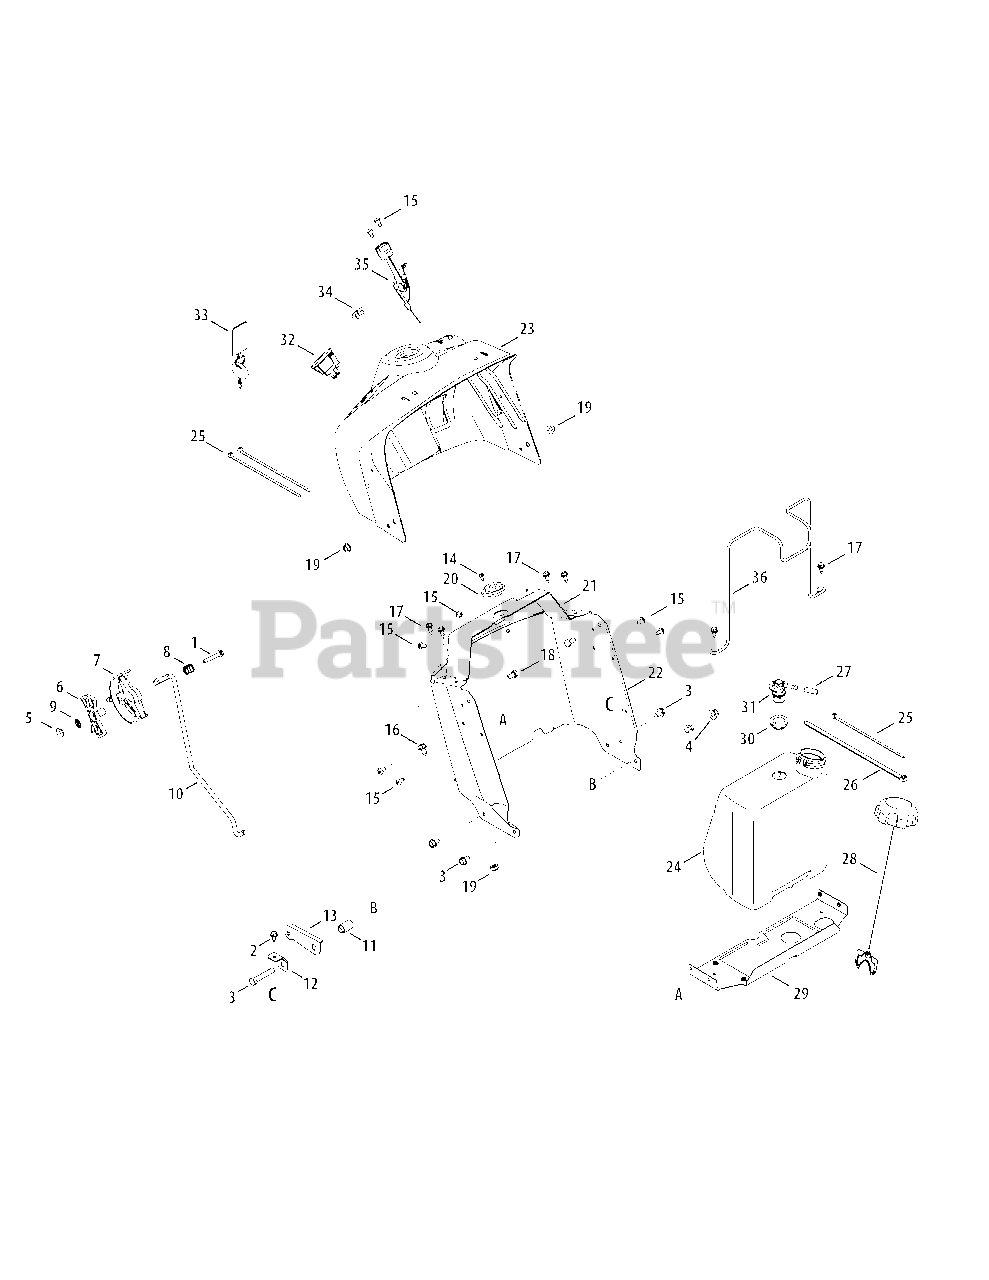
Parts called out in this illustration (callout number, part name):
1	Hex Head Screw, 1/4-20 x 1.50
2	Self-Tap Screw, 1/4-20 x .625
3	Hex Head Screw, 3/8-16 x 2.00
4	Flange Lock Nut, 3/8-16
5	Top Lock Weld Nut, 1/4-20
6	Index Control
7	Shift Lever
8	Compression Spring, .685 x .63
9	Internal Lock Washer, 1/4
10	Speed Control Rod
11	Flange Spacer, .390 x .671 x 1.095
12	Speed Latch Tab
13	Speed Latch
14	Screw, #10
15	Self-Tap Screw, 1/4-20
16	Self-Tap Screw, 5/16-18
17	Hex Washer Screw, 1/4-20 x .625
18	Hex Head Screw, 5/16-18
19	Flange Lock Nut, 5/16-18
20	Steering Column Bearing
21	Steering Support Bracket
22	Lower Dash
23	Upper Dash Panel
24	Fuel Tank
25	Cable Tie, 3/16 x 7.4"
26	Cable Tie, 36" Lg.
27	Vent Hose
28	Fuel Cap
29	Gas Tank Support Bracket
30	Rubber Grommet
31	Fuel Rollover Valve
32	Key Switch Module
33	Key Assembly
34	Choke Plug
35	Throttle/Choke Assembly
36	Fuel Tank Support Rod
